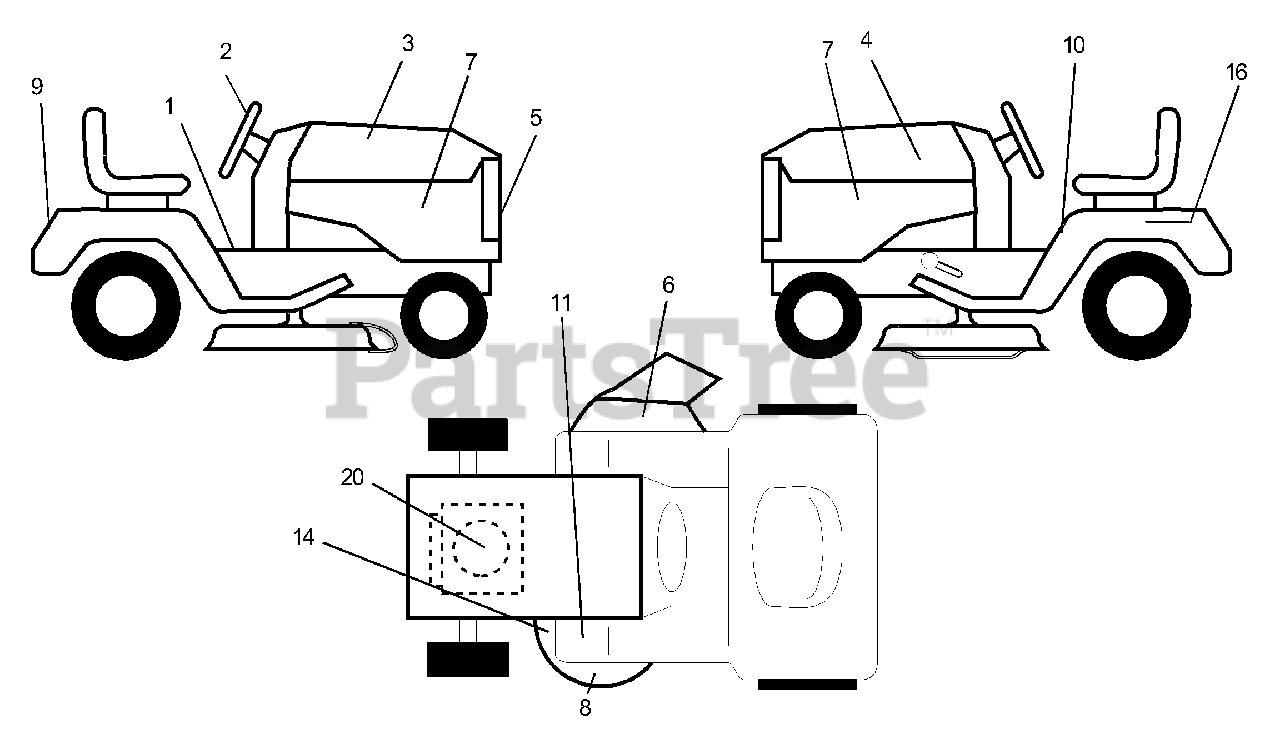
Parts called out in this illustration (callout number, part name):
1	Decal Instruction Operat English
2	Decal Ins Strg Wh
3	Decal Hood Rh
4	Decal Hood Lh
5	Decal Grille Logo
6	Decal, Warning
7	Decal Panel Side
8	Decal Deck Grasseater
9	Decal Fender Logo
10	Decal Danger English
11	Decal Clutch/brake English
14	Decal V-belt Schematic 42"
16	Decal Battery Danger/Poison
20	Decal HP Engine
